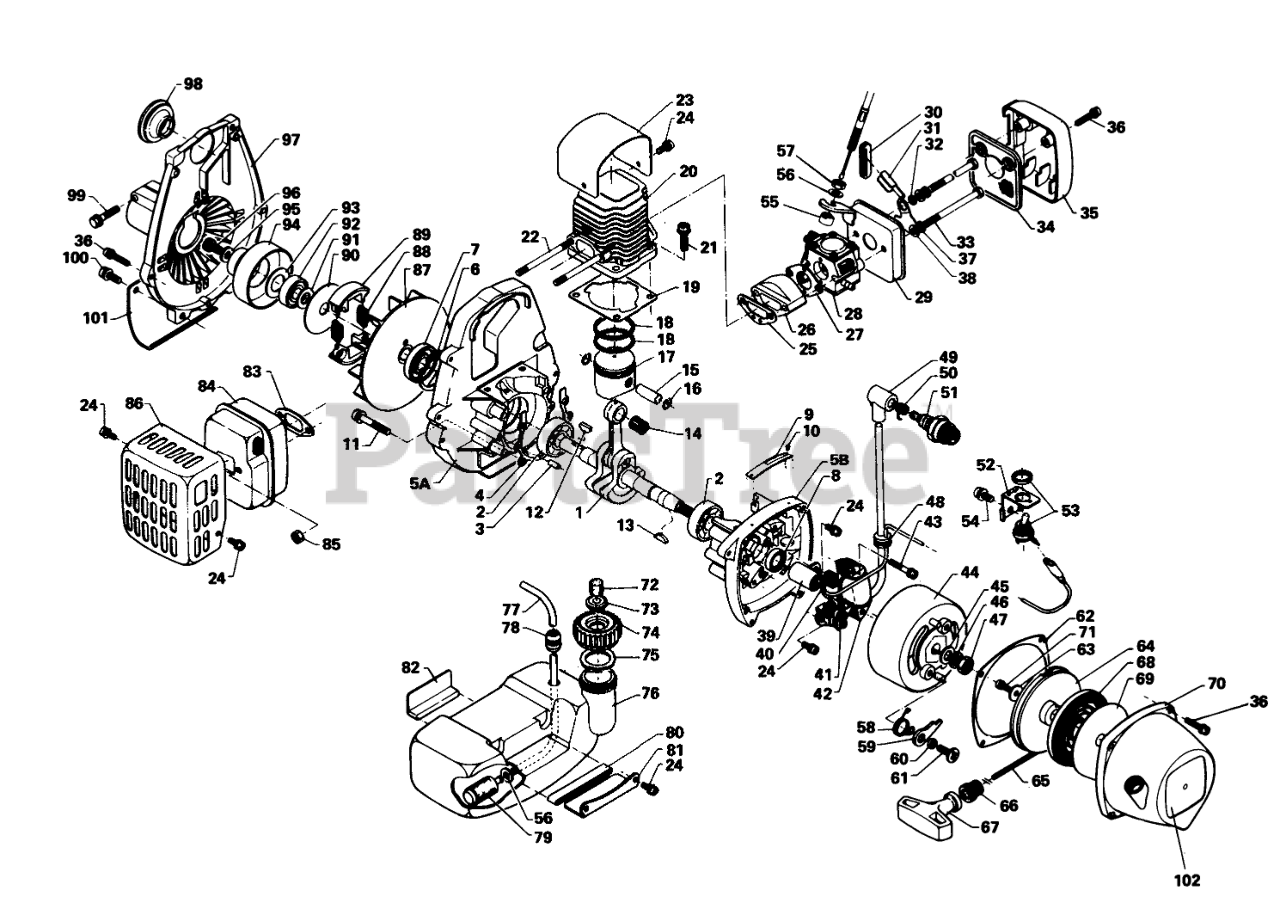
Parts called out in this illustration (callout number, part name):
1	Crankshaft Assembly
2	Bearing
3	Knockpin
4	Gasket, Crankcase
5A	Crankcase Set
5B	Crankcase Set
6	Circlip
7	Oil Seal, Clutch Side
8	Oilseal
9	Model Plate
10	Rivet
11	SCREW
12	Woodruff Key
13	Woodruff Key
14	Needle Bearing
15	Piston Pin
16	Circlip, Piston Pin
17	Piston
18	PISTON RING
19	Gasket, Cylinder Base
20	Cylinder
21	Screw
22	Stud Bolt
23	Cylinder Cover
24	SCREW
25	GASKET
26	Insulator
27	Gasket
28	Carburetor Assembly
29	Case, Air Cleaner
30	GROMMET
31	Choke Shutter
32	Spacer
34	AIR FILTER
35	AIR CLEANER COVER
36	SCREW
37	Washer
38	WASHER
39	CONDENSER
40	Oiler
41	CONTACT BREAKER SET
42	IGNITION COIL
43	Screw
44	Flywheel
45	Washer
46	Spring Washer
48	Grommet
49	Cap-Spark Plug
50	Coil Spring-Plug Cap
51	Spark Plug
52	Bracket, Switch
53	SWITCH STOP
54	SCREW
55	Locknut
56	Washer
58	Ratchet Spring
59	Ratchet
60	RATCHET SPACER
61	Screw
62	Gasket, Starter Case
63	Washer
64	RECOIL DRUM
65	Starter Rope
66	Rope Guide
67	Starter Handle
68	REWIND SPRING
69	SIDE PLT
70	Starter Case
71	SCREW
72	Filter
73	Check Valve
74	Cap, Fuel Tank
75	Gasket-Fuel Tank Cap
76	FUEL TANK
77	FUEL PIPE
78	GROMMET
79	Fuel Strainer
80	Cushion
81	Bracket Fuel Tank
82	Cushion
83	Gasket, Muffler
84	Muffler
86	Muffler Cover
88	CLUTCH SPRING
89	CLUTCH SHOE
90	Side Plate
91	Spacer
92	Ball Bearing
93	Spacer
94	Clutch Drum
95	Washer
97	Fan Cover
98	Boot, Plug Cap
100	SCREW
101	Bracket
102	Decal, 2100
